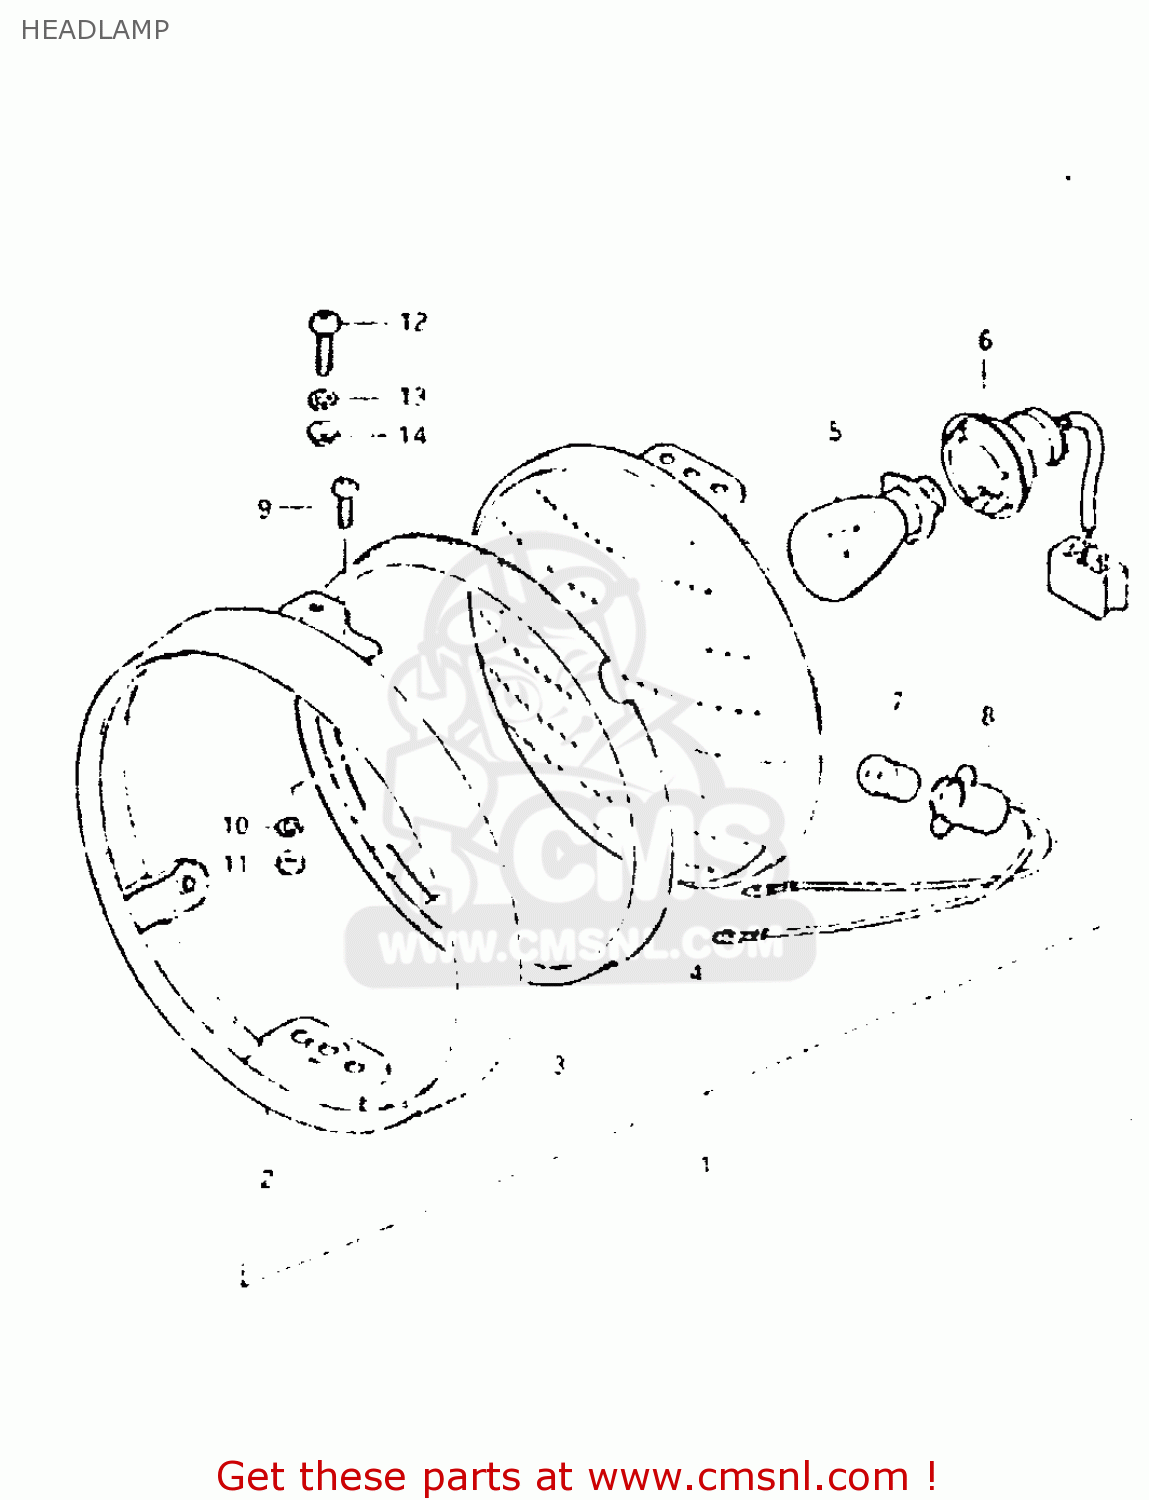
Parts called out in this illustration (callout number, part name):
1	HEADLAMP ASSY
2	RIM
3	RETAINER,HEADLAMP
4	UNIT, HEAD LIGHT
5	BULB 12V35/35W
6	SOCKET
7	BULB(12V3.4W,STANLEY,A72A)
8	SOCKET
9	SCREW
10	LOCK WASHER
11	NUT
12	SCREW
13	WASHER,LOCK
14	WASHER
